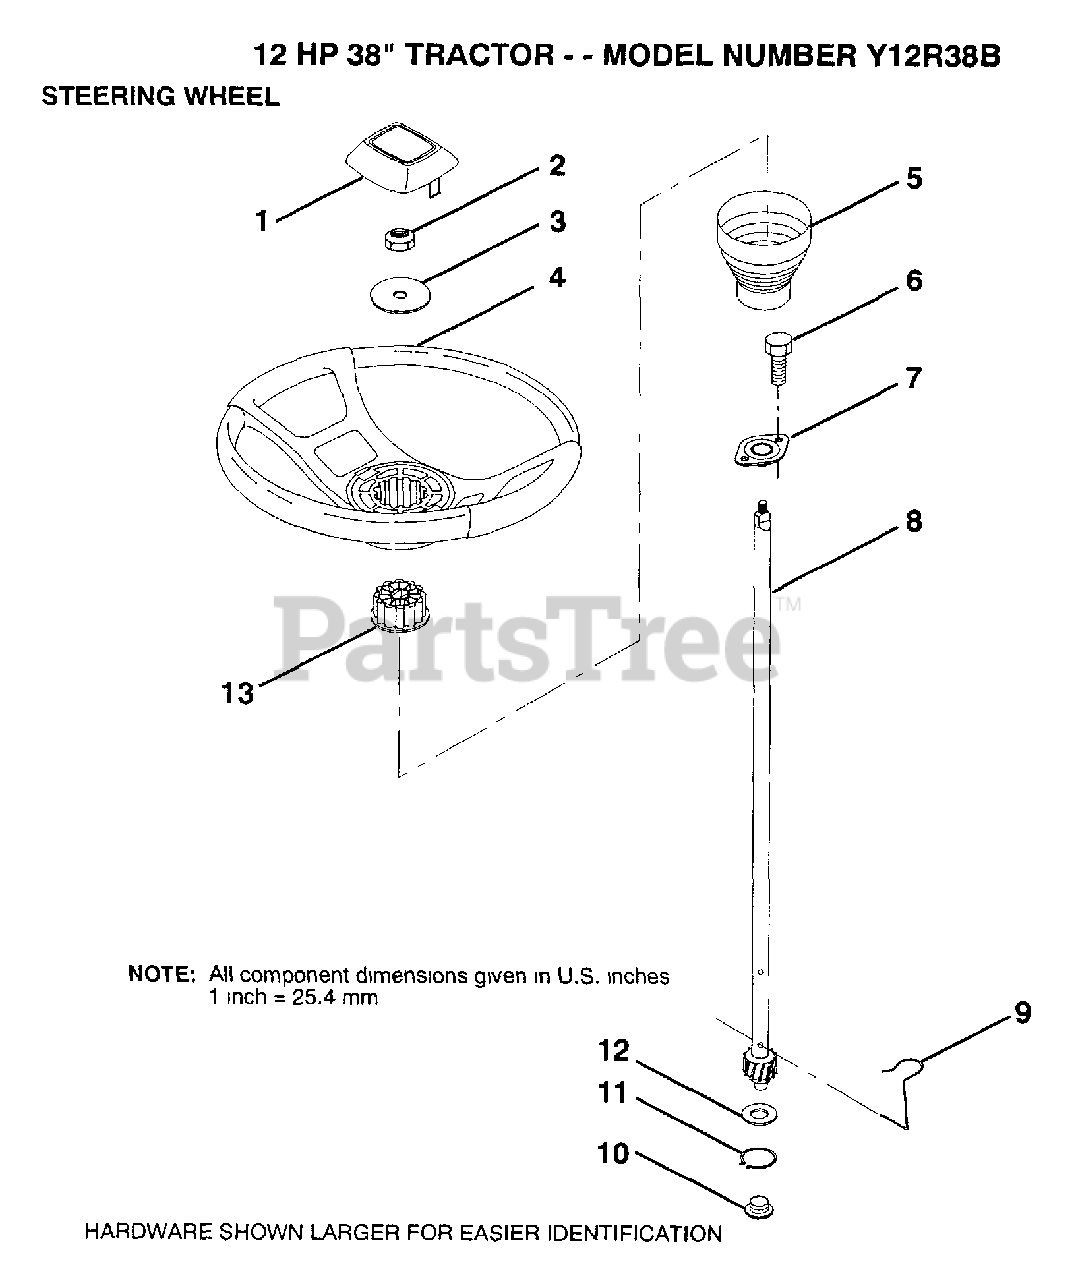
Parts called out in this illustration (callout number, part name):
1	ST WHL INSERT CAP
2	GRIPCO NUT
3	WASHER T
5	SLEEVE STEERING
9	STEERING CLIP
10	BUSHING STEER LWR
11	RING
12	WASHER LT
13	ADAPTER-WHEEL LT
